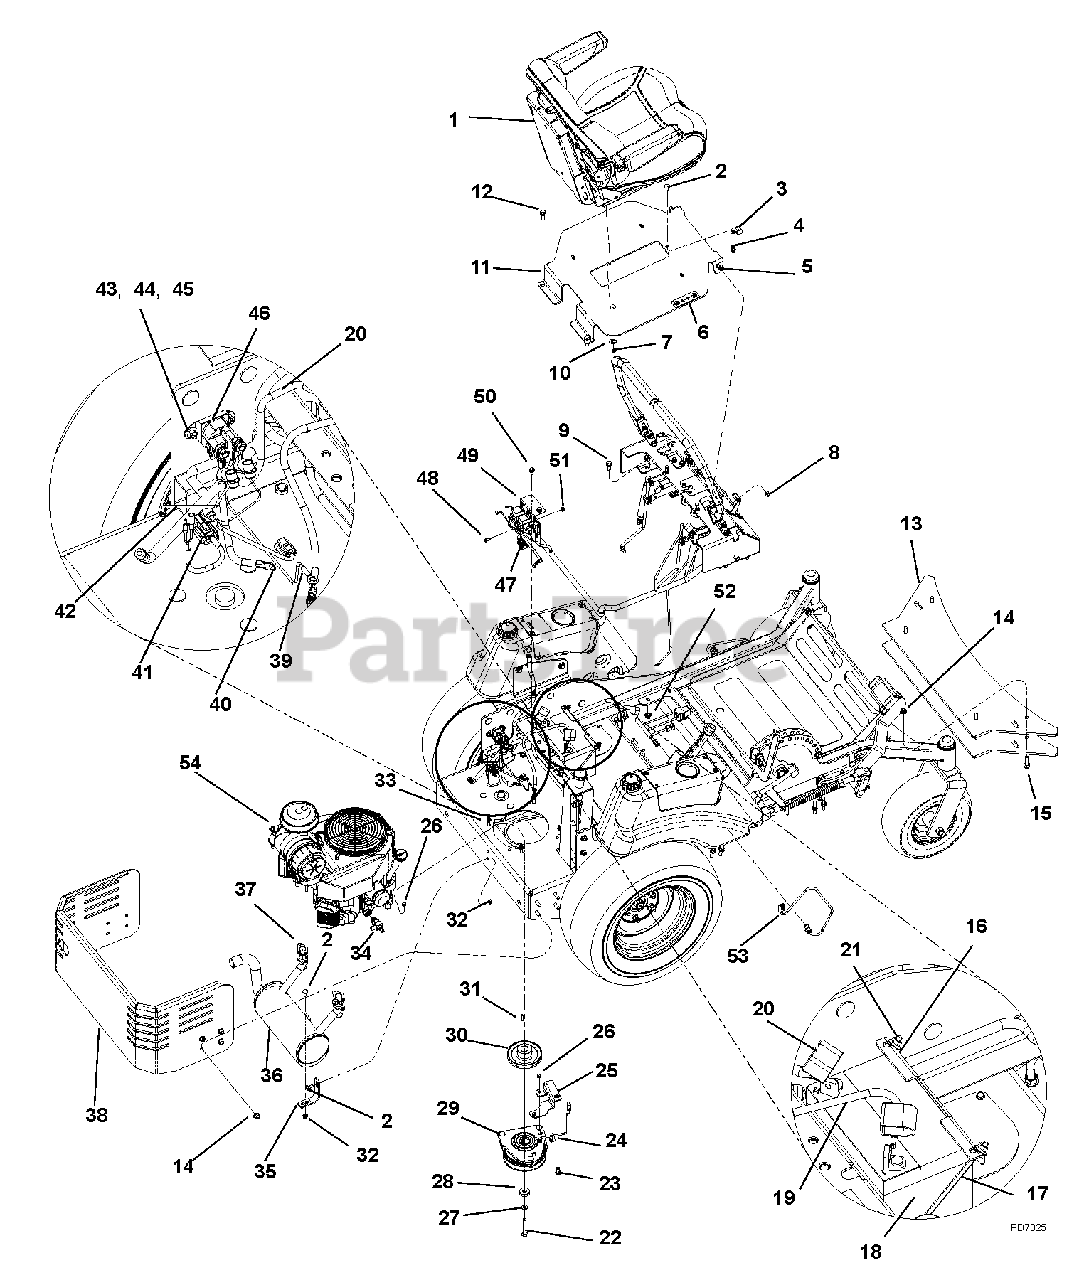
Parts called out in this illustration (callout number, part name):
1	SEAT, FULL SUSPENSION
2	BOLT, M8 X 1.25 X 20 CRG 8.8 Y
3	P-CLIP, .750 INSULATED
4	LOCKNUT, FL, ISO7043, M8 X 1.25
5	BOLT, 1/2 X 1.06 X 3/8-16 SLD 5 Y
6	LABEL - PARK BRAKE DIRECTION
7	LOCKNUT, 5/16-18 NYLOCK Y
8	NUT, 3/8 LOCK
9	SCREW, HEX M10 X 1.5 X 25
10	WASHER, .344 X 1.00 X .134 FLAT Y
11	PLATE, SEAT S/O
12	SCREW, HEX , FL, JDS123, M10 X 1.5 X 30
13	PLATE, WEIGHT
14	LOCKNUT, FL, ISO7044, M10-1.50
15	SCREW, HEX , FL, JDS121, M10 X 1.5 X 40
16	HOLDER, BATTERY
18	BATTERY, 12V-U1-CCA 400 MIN
19	CABLE, BATTERY - 20" GROUND
20	CABLE, BATTERY POSITIVE
21	NUT-1/4" FLANGE PREVAILING TORQUE
22	BOLT, 7/16-20 X 2.75 HEX 5 Y
23	BOLT, 7/16-14 X .750 HEX 5 Y
24	CABLE TIE, .31 X 14.6 - BLACK
25	PLATE, CLUTCH DOG
26	LOCKNUT, 5/16-18 CROWN Y
27	WASHER, .438 MED SPRG LOCK Y
28	SPACER, .468 X 1.38 X .375 Y
29	CLUTCH ASSY, OGURA
30	PULLEY, V-BELT 4.78PD X 1.000 W/KEY
31	KEY, .250 X .250 X .995 TPR
32	LOCKNUT, M8 X 1.25, FLANGED ZN
33	BOLT, 5/16-18 X 1.75 HEX 5 Y
34	OIL DRAIN FITTING
35	BRACKET, MUFFLER
36	MUFFLER, CHARIOT ACS KAI
37	GASKET, MUFFLER
38	BUMPER, REAR EKW
39	WIRE, GROUNDWIRE, EFI FUEL PUMP
40	CABLE, 12" STARTER
41	HARNESS, PIGTAIL
42	FUSIBLE LINK, 10"
43	BOLT, 1/4-20 X .750 HEX 5 Y
44	LOCKNUT, 1/4-20 CENTER Y
45	WASHER, .250 REG FLAT Y
46	SOLENOID, 12 V STARTER
47	RELAY, SEALED W/BRACKET
48	SCREW, HEX JDS123, M6 X 1 X 16 Z
49	BRACKET, ELECTRIC MOUNTING
50	SCREW, HEX , FL, JDS123, M8 X 1.25 X 16
51	LOCKNUT, F1.ISO7043M6 X 1-10
52	LOCKNUT, M10 X 1.50 WHIZ GR10 Y
53	HARNESS, WIRING
54	ENGINE, KAWASAKI 19HP FH580V
